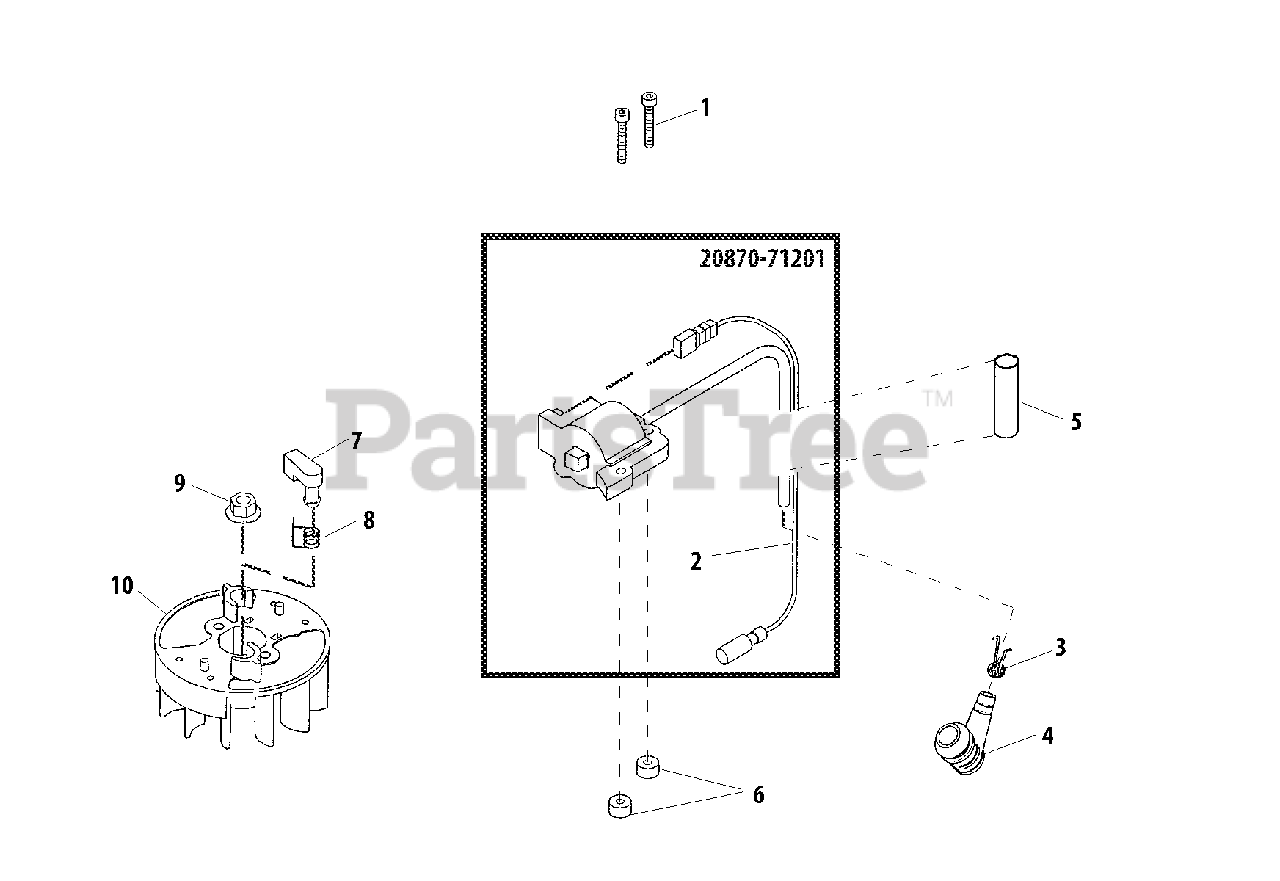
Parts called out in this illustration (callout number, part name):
1	BOLT M4×26
2	WIRE
3	TERMINAL, SPARK PLUG
4	CAP, SPARK PLUG
5	TUBE, IGNITION COIL
6	INSULATOR 4.2×11×6
7	PAWL
8	SPRING, TORSION
9	NUT M8
10	FLYWHEEL
20870-71201	IGNITION COIL ASSY
